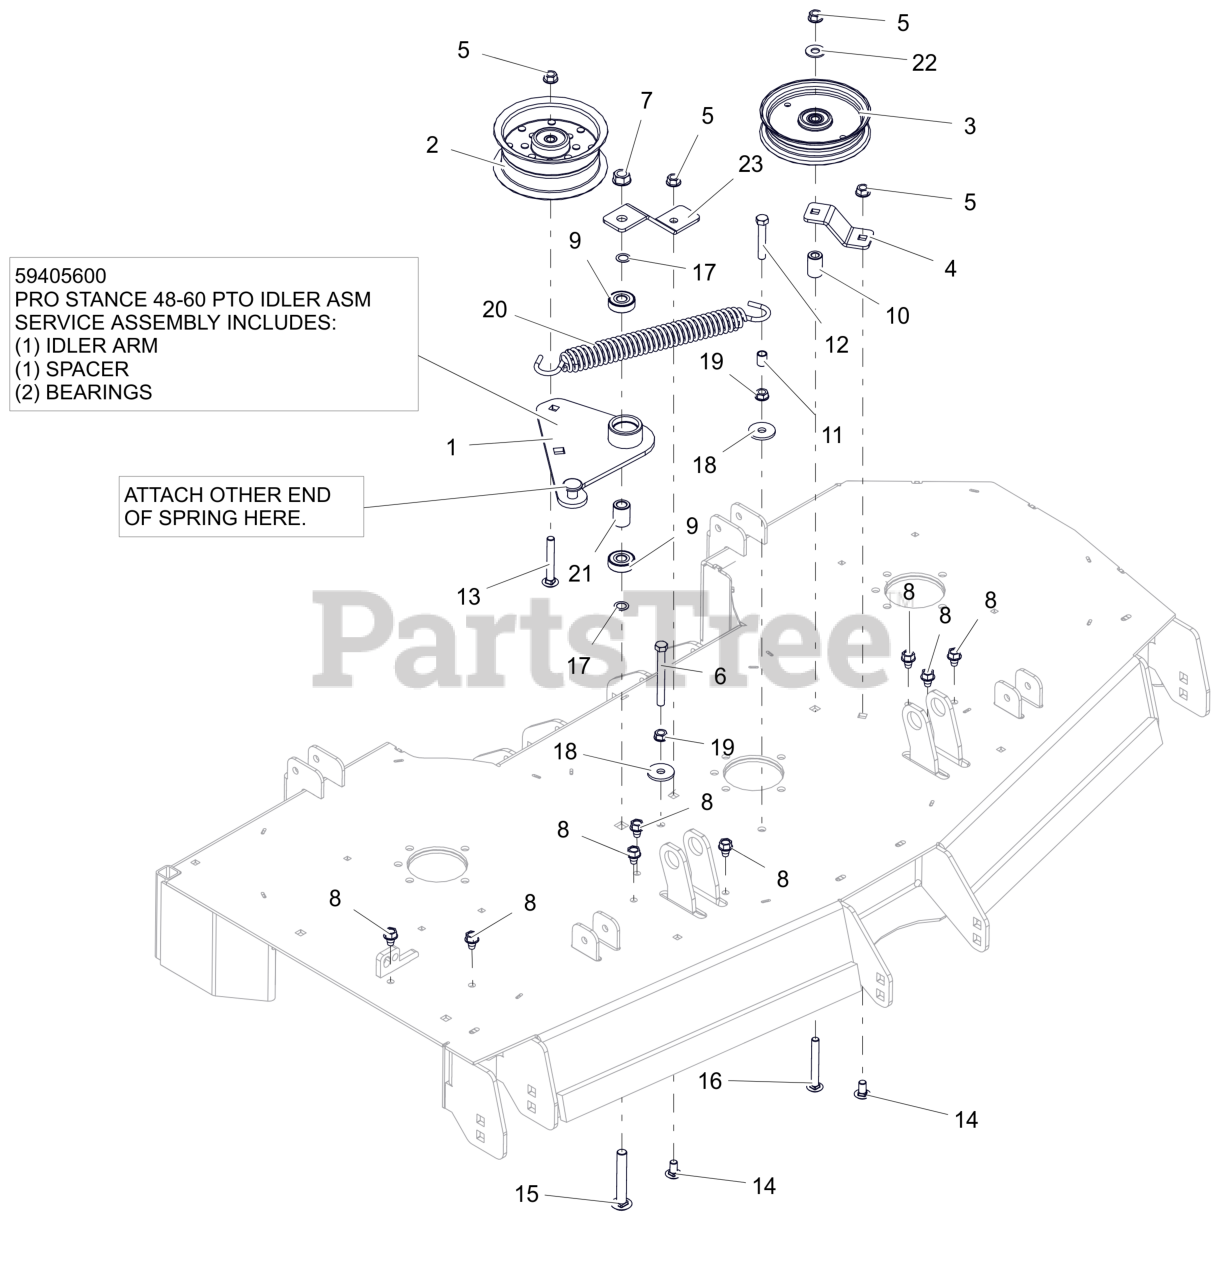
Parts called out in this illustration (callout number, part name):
1	WLDMT, PTO IDLER ARM
1	PTO IDLER ASSEMBLY
2	PULLEY, FLAT 5.00X2.36X.375
3	IDLER- FLAT - 5.00" X .75"
4	PTO FIXED IDLER MTG BRKT -RED
5	NUT-LK-CTR-FLG .375-16 GF ZCC
6	BLT, HEX .38-16X3.50 G5 ZCC
7	NUT-LK-CTR-FLG .500-13 GG ZCC
8	SCR,TAP .375-16X.50 HWH TR ZCC
9	BRG-BALL .500X1.38X.437
10	BUSHING, SLV .380X.750X1.190
11	SPCR, SLV .385X.500X.652
12	BLT,HEX .38-16X2.25 G5 ZCC
13	BLT, RHSN .38-16X2.75 G5 ZCC
14	BTL,RHSSN .375-16 X 0.75 G5 FPB
15	BTL,RHSSN .500-13 X 3.25 G5 ZCC
16	BTL,RHSSN .375-16 X 3 G5 ZCC
17	WASHER, .500X.750X.020 THRUST
18	WSHR,FLT .406X1.375X.135 ZCC
19	NUT, SPNLK-FLG .38-16 G5 ZCC
20	SPRING, EXTENSION
21	SPACER .510 X .867 X 1.1485
22	WSHR,FLT .438X1.00X.083 ZCC
23	BRKT- PROSTANCE PTO IDLER(RED)
